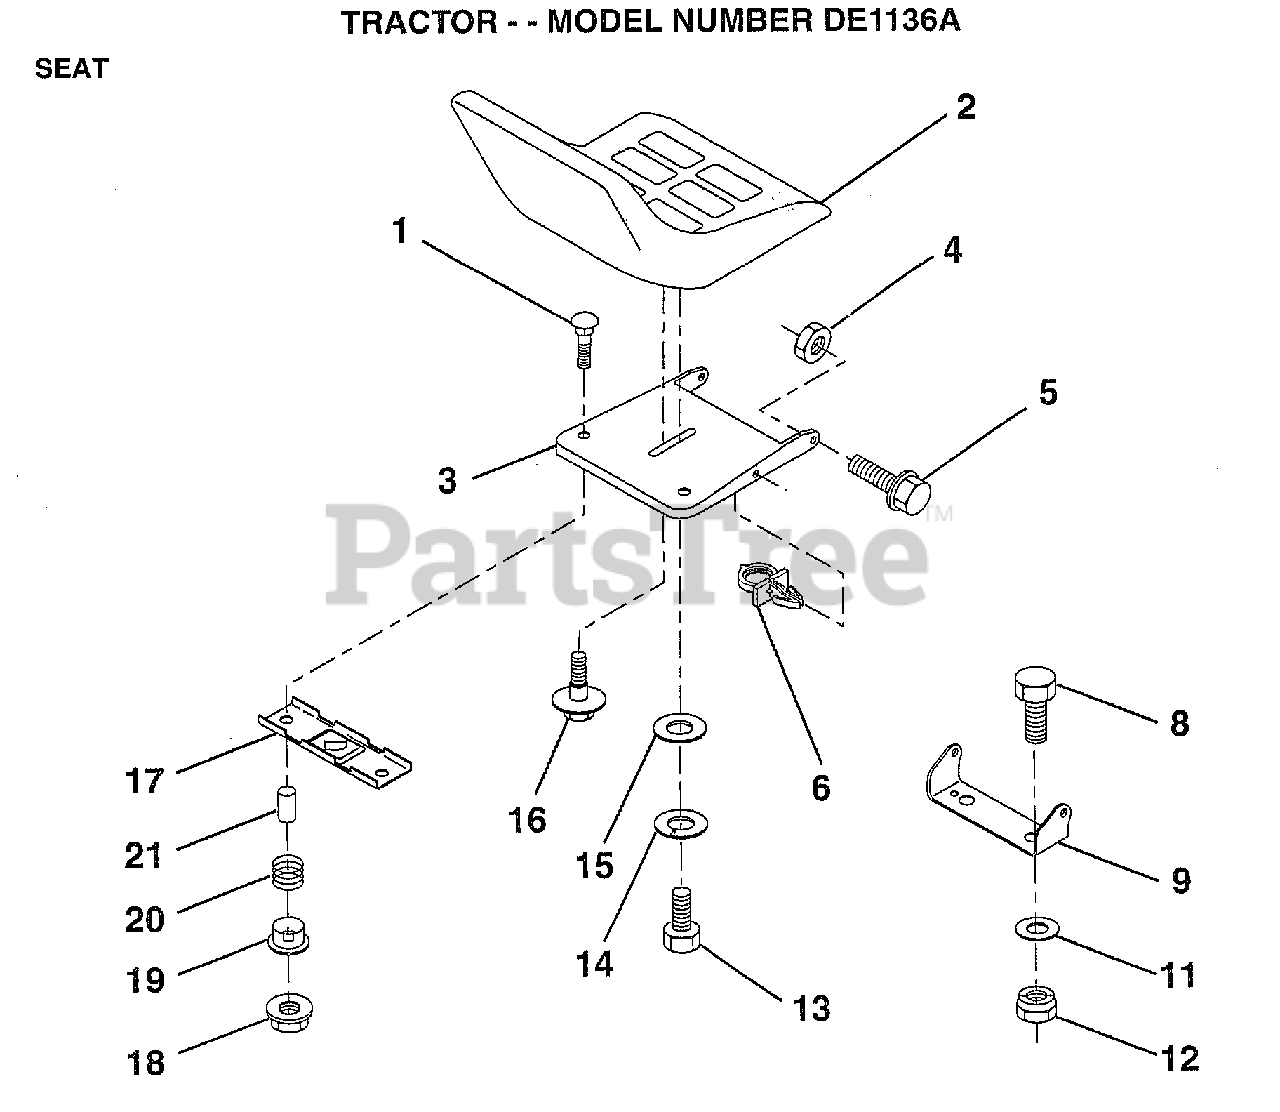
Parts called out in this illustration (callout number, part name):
1	BOLT-RD HD SQ NK
3	PAN-SEAT
4	NUT
5	"BOLT,SHOULDER"
6	CLIP.PUSH-IN.HING
8	BOLT
9	BRACKET PVT SEAT
11	WASHER
12	NUT
13	BOLT
14	LOCKWASHER
15	WASHER
16	"BOLT,SHOULDER"
17	BRKT SWITCH
19	BUSHING
20	SPRING
21	SPLIT SPACER
